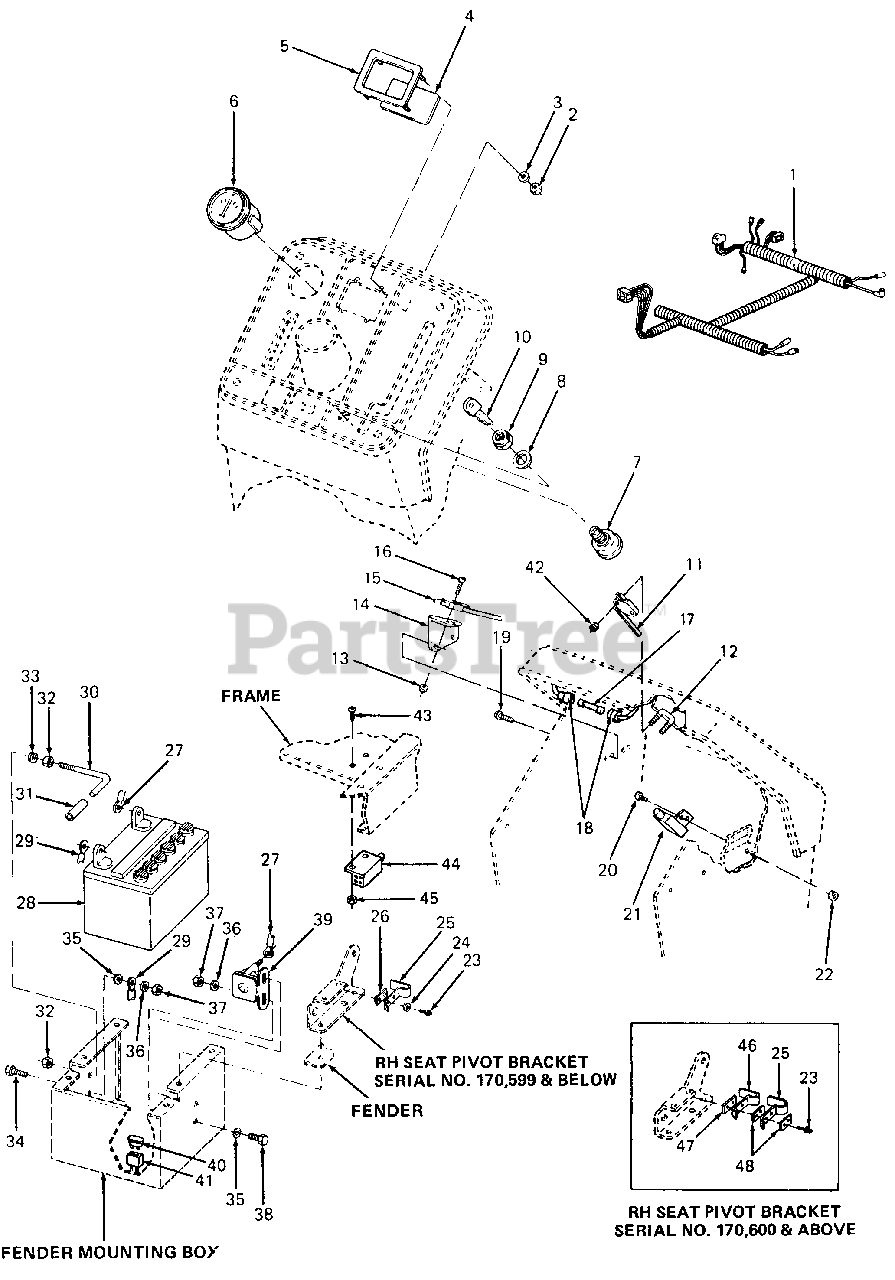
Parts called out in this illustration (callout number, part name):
1	Harness, Wire
2	Nut, Self-Threading
3	Washer, Rubber, .18 X .50 X .06 Thk
4	Label, Indicator
5	Bezel, Light
6	Ammeter
7	Switch, Ignition Key
8	Washer, Flat
9	Nut, Ignition Switch
10	Key, Ignition (Set of 2)
11	Switch, Rev. Micro
12	Screw, Switch
13	Nut, Hex Insert Lock, #4-40
14	Plate, Switch
15	Switch, Micro
16	Screw, Hex Hd Mach, #4-40 X .75 Lg
17	Fuse, 20 Amp Slo-Blow
18	Fuse Holder
19	Screw, Hex AB Tapp, 1/4 X .62 Lg
20	Screw, Truss Mach, #10-24 X .50 Lg
21	Switch, Safety
22	Nut, Hex Center Lock, #10-24
23	Screw, Hex Wash Hd AB Tapp, #8 X .50 Lg
24	Washer, Plastic
25	Switch, Spring
26	Plate, Insulator Nut
27	Wire, Positive Battery
28	Battery, 12 Volt
29	Wire, Ground, 11.5 in. Lg
30	Pin, Belt Guard Lock
31	Fuel Line, 2 in. Lg
32	Nut, Hex, 5/16-24 GR5
33	Washer, Lock, 5/16
34	Screw, Hex Cap, 1/4-20 X .62 Lg GR5
35	Washer, Int Ext Lock, 1/4 X 3/4
36	Washer, Flat, .281 X .73 X .063 Thk
37	Nut, Hex Patch Lock, 1/4-20
38	Screw, Hex Cap, 1/4-20 X .50 Lg GR5
39	Solenoid, 12 Volt
40	Fuse, Auto Type, 20 Amp
41	Fuse Holder
42	Nut, Hex Insert Lock, #4-40
43	Screw, #10-24 X .50 Lg
44	Switch, Double Poled Plunger
45	Nut, Hex Center Lock, #10-24
46	Switch, Spring
47	Plate, Insulator Boss
48	Plate, Insulator
